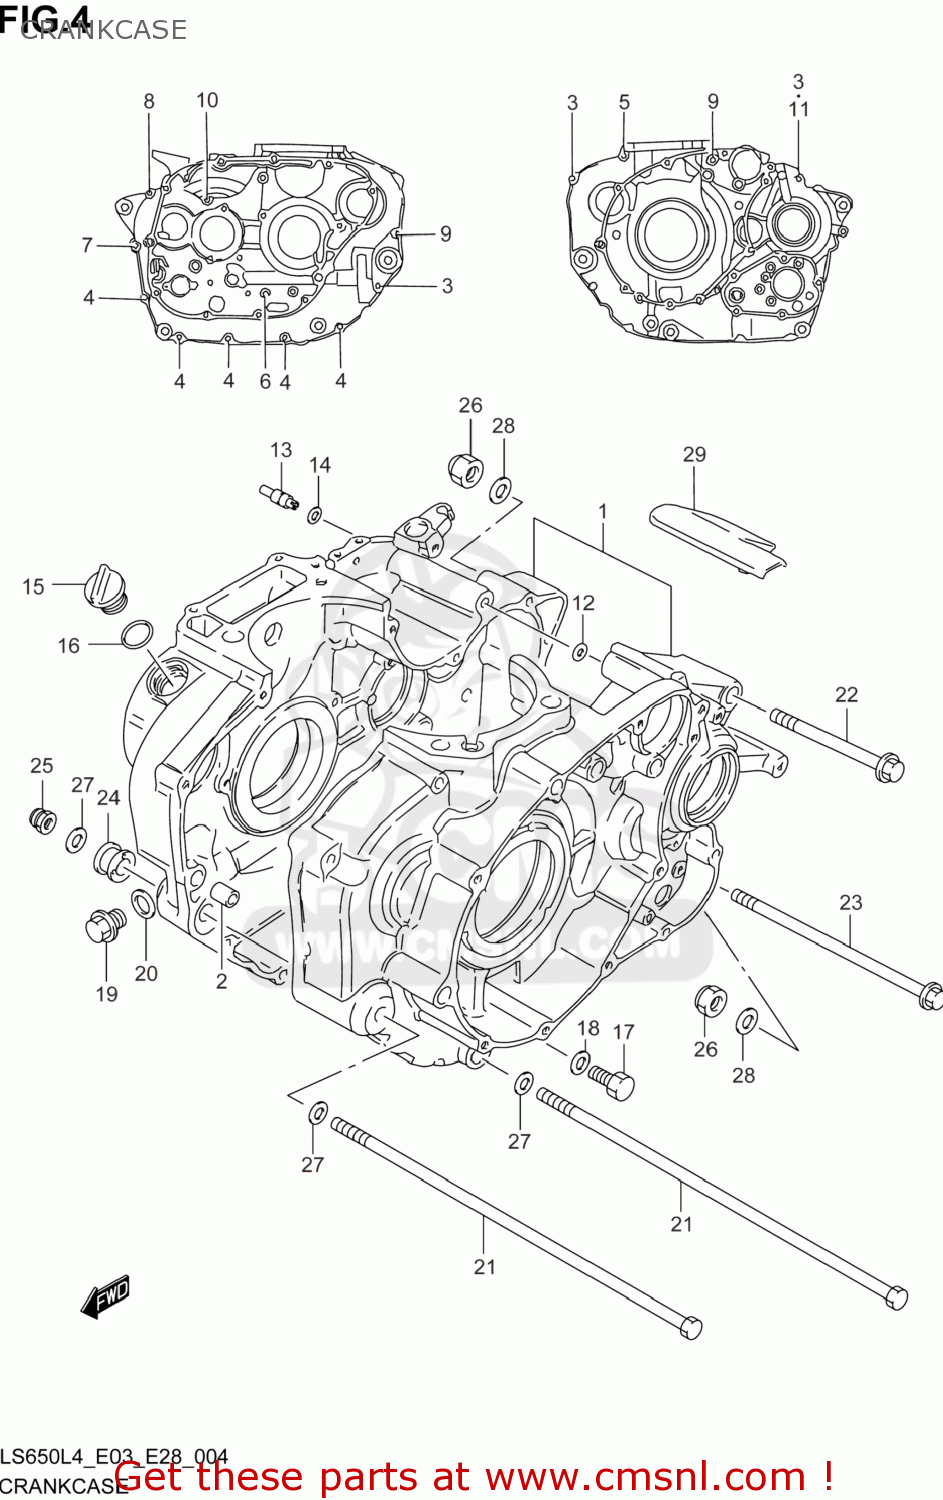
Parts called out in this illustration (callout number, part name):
1	CRANKCASE SET
2	PIN(8.4X11X20)
3	BOLT
4	BOLT
5	BOLT
6	BOLT
7	BOLT
8	BOLT
9	BOLT
10	BOLT
11	GASKET(5.8X13X1.2) (NAS)
12	O RING(D:2.4,ID:9.6)
13	JET,OIL GALLERY(18)
14	O RING(D:1.2,ID:4)
15	PLUG,ENGINE OIL FILLER
16	O RING(D:3.1,ID:16.8)
17	PLUG(12X20)
18	GASKET(12.1X16.2X3.7) (NAS)
19	PLUG(14X12)
20	GASKET(13.8X18.8X4.8) (NAS)
21	BOLT(10X323)
22	BOLT(10X105)
23	BOLT(10X180)
24	SPACER,ENGINE MOUNT(L20)
25	NUT
26	NUT
27	WASHER
28	WASHER
29	COVER,CRANKCASE START MOT
